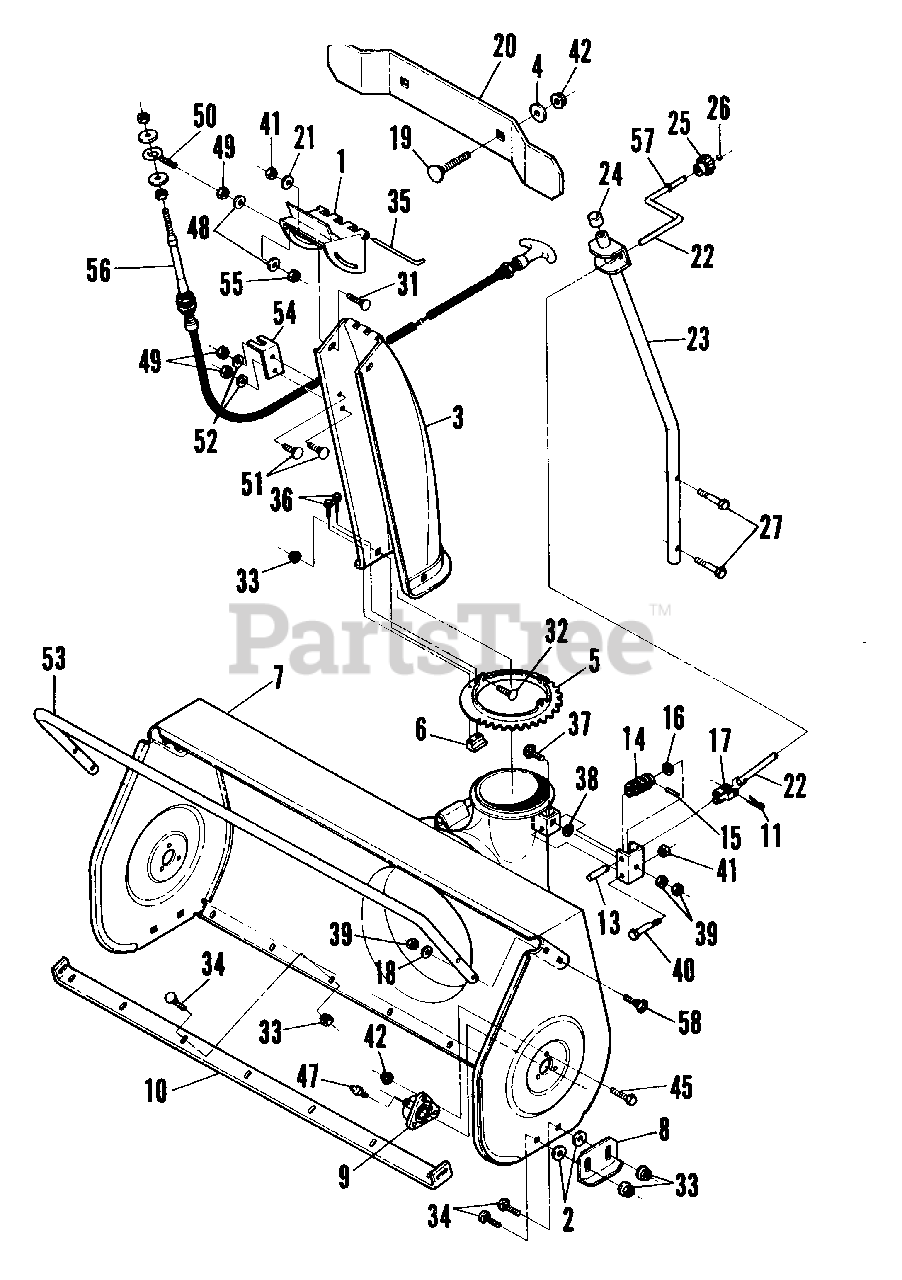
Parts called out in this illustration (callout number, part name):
1	DEFLECTOR, Discharge
2	WASHER, 5/16"
3	CHUTE & DECAL ASS'Y.
4	WASHER, 1/4" Flat
5	RING, Chute
6	RETAINER, Chute Ring
7	HOUSING & DECAL ASS'Y.
8	SHOE, Skid
9	BEARING, Auger Shaft
10	BLADE, Scraper
11	PIN, 1/8 x 1-1/4" Cotter
13	SHAFT, Worm
14	WORM
15	ROLL-PIN, 1/8 x 3/4"
16	WASHER, Spring Steel
17	CONNECTOR
18	SPLIT LOCK WASHER
19	BOLT, 1/4 - 20 x 5/8" Flat Head Carriage
20	DEFLECTOR, Exhaust
21	WASHER, 5/16" Flat
22	CRANK, Chute
23	BRACE, Chute Crank
24	CAP, Crank Brace
25	KNOB, Chute Crank
26	NUT, 5/16 - 18 Hex Lock
27	SCREW, 5/16 - 18 x 1 1/2" Self Tap
31	SCREW, 5/16 - 24 x 3/4" Hex Head Cap
32	BOLT, 5/16 - 18 x 5/8" Carriage
33	NUT, 5/16 - 18 Hex Flange Lock
34	BOLT, 5/16 - 18 x 3/4" Carriage
35	PIN, Hinge
36	SCREW, #10 - 24 x 5/8" Self-Tapping
37	BOLT, 5/16 - 18 x 1" Carriage
38	RETAINER, Bolt
39	NUT, 5/16 - 18 Hex
40	SCREW, 5/16 - 24 x 2 1/2" Hex Head Cap
41	NUT, 5/16 - 24 Hex Lock
42	NUT, 1/4-20 Hex Flange Lock
45	BOLT, 1/4 - 20 x 3/4" Hex Flange Lock
47	FITTING, Lube (Press fit for .187 hole-no ball)
48	WASHER, 1/4" Flat
49	NUT, 1/4 - 20 Hex
50	BOLT, 1/4 - 20 Eye
51	BOLT, 1/4 - 20 x 1/2" Carriage
52	WASHER, 1/4" Internal Tooth Lock
53	CUTTER, DRIFT
54	MOUNT, CABLE
55	NUT, 1/4 - 20 Hex Center Lock
56	CABLE, Control
57	BUSHING
58	BOLT, 5/16 - 18 x 1 1/2" Curved Head
